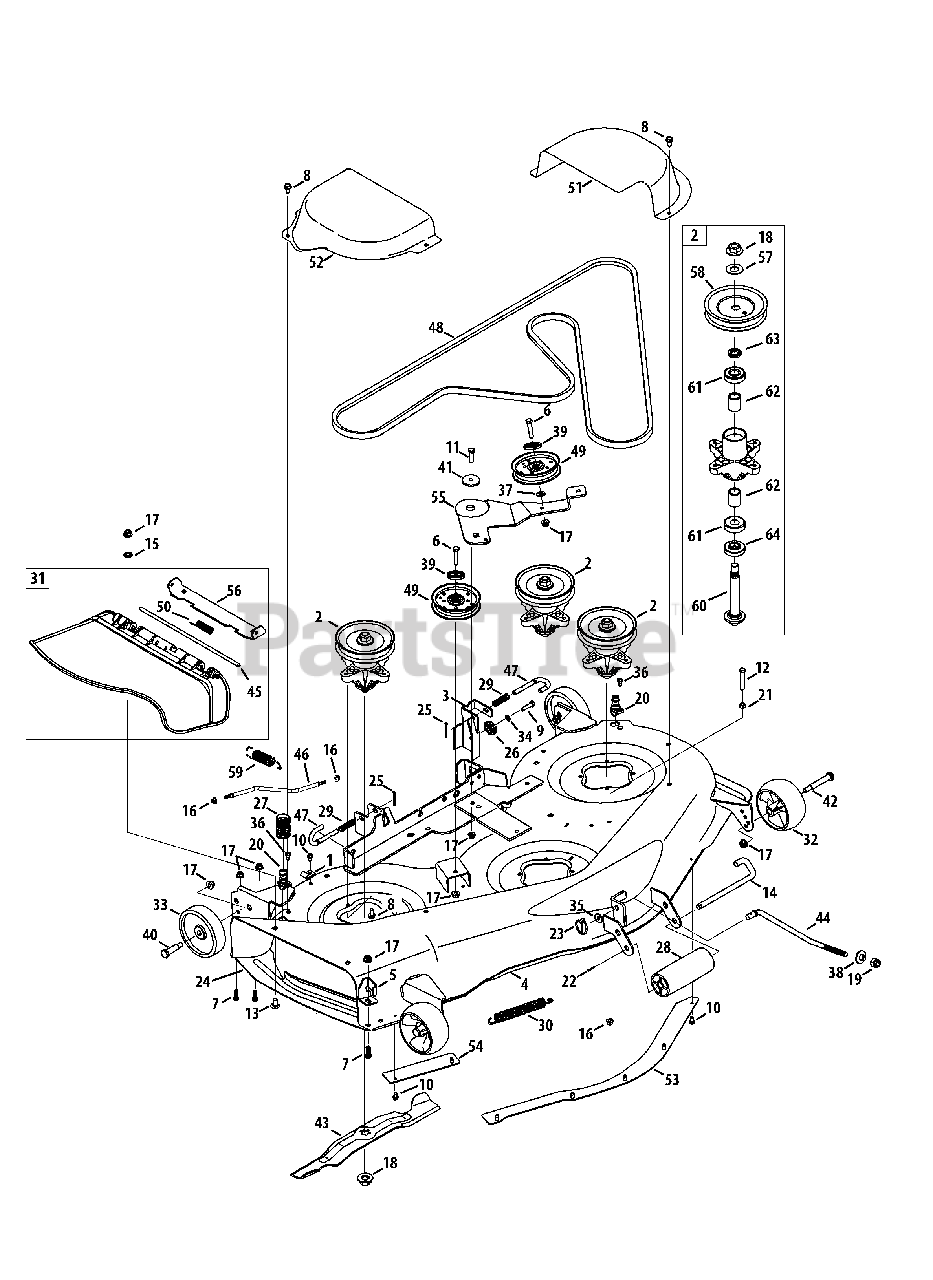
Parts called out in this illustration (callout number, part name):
1	Bracket, Hook, Retainer
2	Spindle Assembly, Pulley, 5.39 Dia.
3	Bracket Assembly, Deck, Hanger LH
4	Deck, 50"
5	Stop, Chute, Deflector
6	Hex Screw, 3/8-16, 1.75, Gr5
7	Hex Screw, 3/8-16, 1.00, Gr5, Spec
8	Screw, Self-tapping, 5/16-18, .750,
9	Hex Screw, 5/16-18, 1.25, Gr5, Std
10	Screw, Self-tapping, 1/4-20, 0.500
11	Hex Screw, 3/8-16, 1.25
12	Hex Screw, 5/16-18, 2.00, Gr5, Std
13	Bolt, Carriage, 3/8-16, 0.75, Gr1
14	Roller Pin-1/2 Dia. x 7.31
15	Nut, Push, 3/8
16	Nut, Flange Lock, 5/16-18, Nylon
17	Nut, Flange Lock, 3/8-16, Nylon
18	Nut, Flange, 5/8-18
19	Nut, 1/2-13
20	Deck Wash Nozzle
21	Nut, Hex, 5/16-18, Gr5
22	Pin, Cotter, 3/32, 1.0
23	Pin, Lynch, .1875
25	Pin, Cotter, 1/8 x 1.25
26	Gear, Deck, Adjustment
27	Coupler, Water
28	Roller, Front
29	Spring, Compression, .535 OD x 1.751
30	Spring, Extension, .94 OD x 6.74
31	Chute Assembly
32	Wheel, Deck, 5.0 Dia. Ball
33	Wheel, Deck 5.0 x 1.38
34	Washer, Lock, 5/16, Regular Duty
35	Washer, Flat, .531 x 1.25 x .100
36	Shoulder Screw, 1/4-20 x 0.50
37	Washer, Flat, .406 x .875 x .059
38	Washer, Bell, .63 x 1.25 x .18
39	Pulley Cap
40	Bolt, Shoulder, .496 x 1.525, 3/8-16
41	Spacer, Shoulder, .8840 x .190
42	Bolt, Shoulder, .496 x 2.50, 3/8-16
43	Blade, 17.90 Star 2 In 1
44	Rod, Lift, Deck, Front, 11.7
45	Pin, Hinge, .3175 Dia. x 14.06 ,1
47	Rod, Deck Release
48	Belt, V-Type
49	Pulley, Idler, 4.25"Dia.
50	Spring, Torsion, .44 I.D. x 2.0,
51	Cover, Belt, LH 50"
52	Cover, Belt, RH 50"
53	Skirt, Center, 50"
54	Skirt, RH, 50"
55	Bracket, Idler, 50" w/o Spacer
56	Bracket, Chute 50/54"
57	Washer, Flat, .760 X 1.50 X .120
58	Pulley, Deck, 5.39 Dia.
59	Spring, Extension, 1.15 OD x 5.99
60	Shaft, Spindle, 5.75 Lg.
61	Bearing, Ball, .787id x 1.85 Od x .551
62	Spacer, .80 x 1.10 x 1.322
63	Spacer, .790 x 1.25 x .175
64	Spacer, .79 x 1.82 x .55lg.
